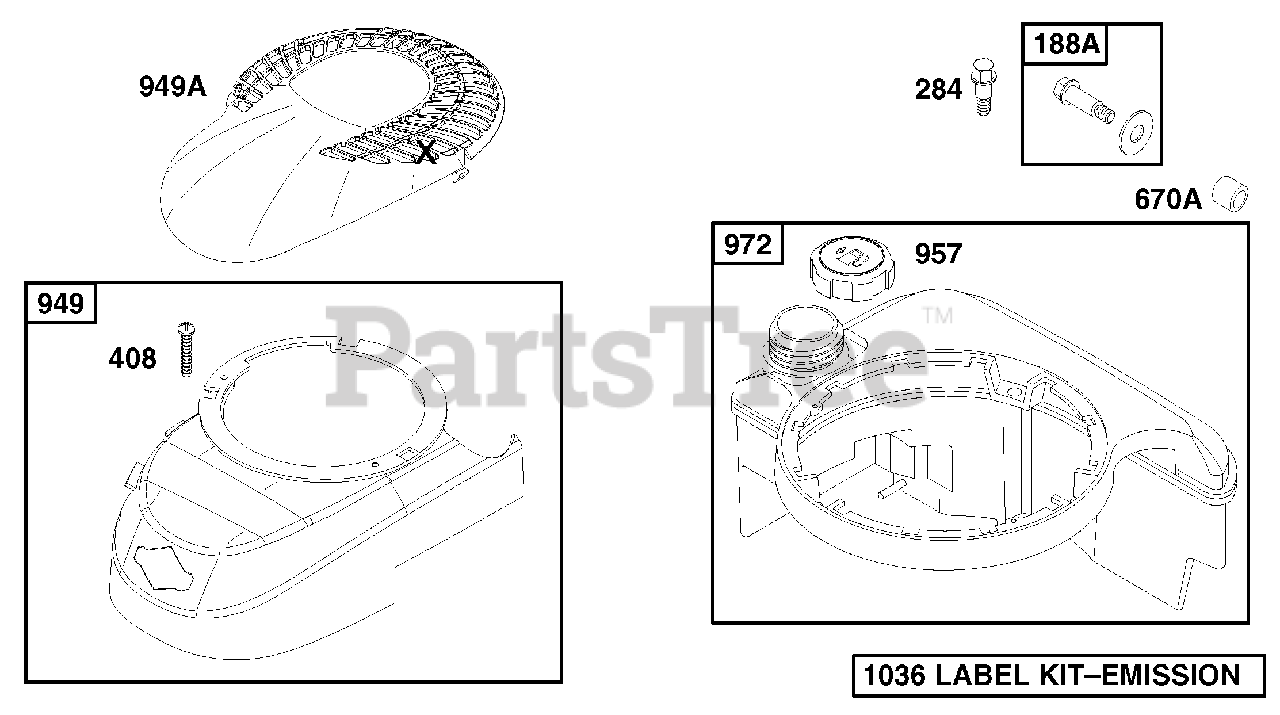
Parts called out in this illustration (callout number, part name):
188A	Screw-Washer Kit
284	Screw-Shoulder
408	Screw-Phillips
670A	Spacer-Fuel Tank
949	Guard-Rewind
949A	Guard-Rewind
957	Cap-Fuel Tank
972	Tank-Fuel
1036	Label Kit-Emission
